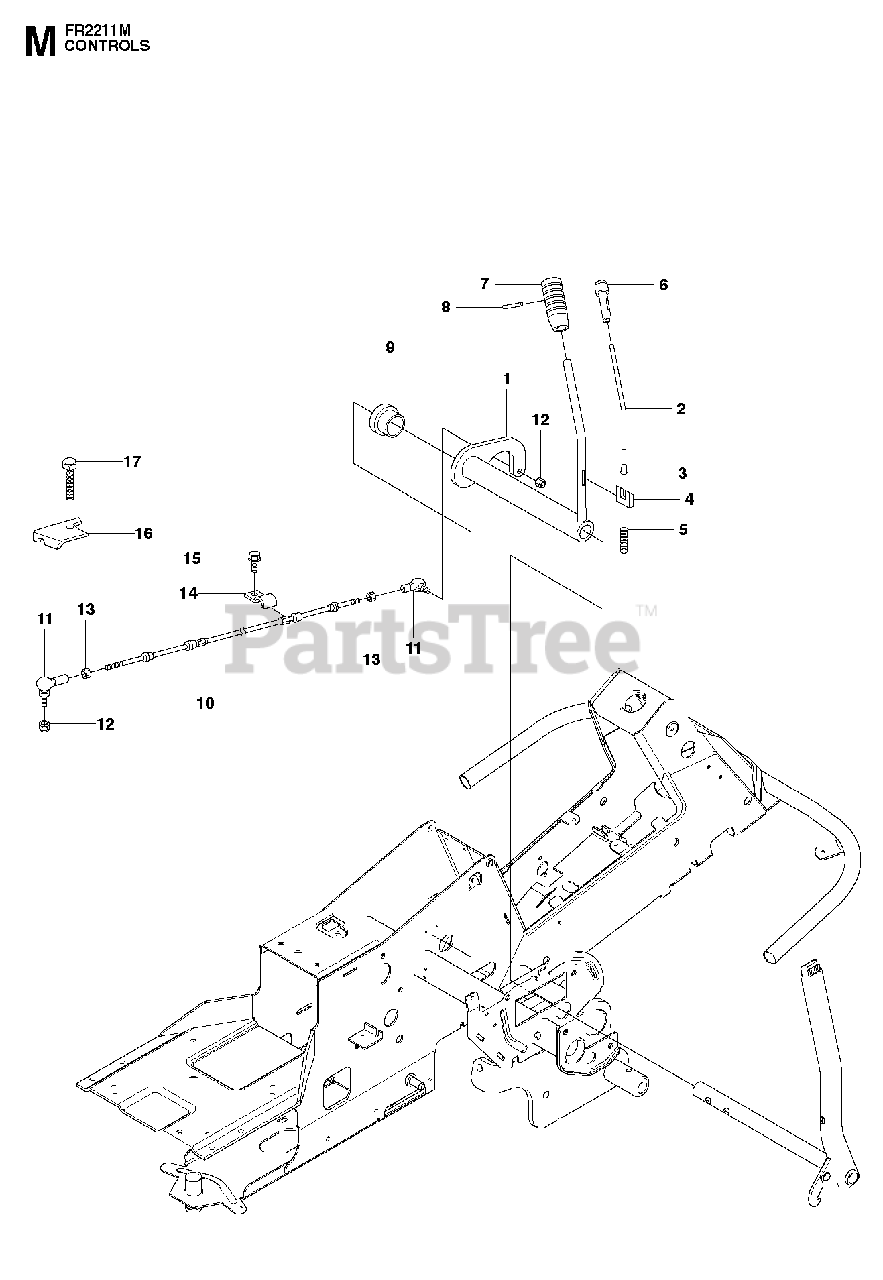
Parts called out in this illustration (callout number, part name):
3	END PIECE
8	SPRING PIN 3X24
9	BUSH
10	CONTROL CABLE
11	CONNECTOR
12	LOCKNUT M5
